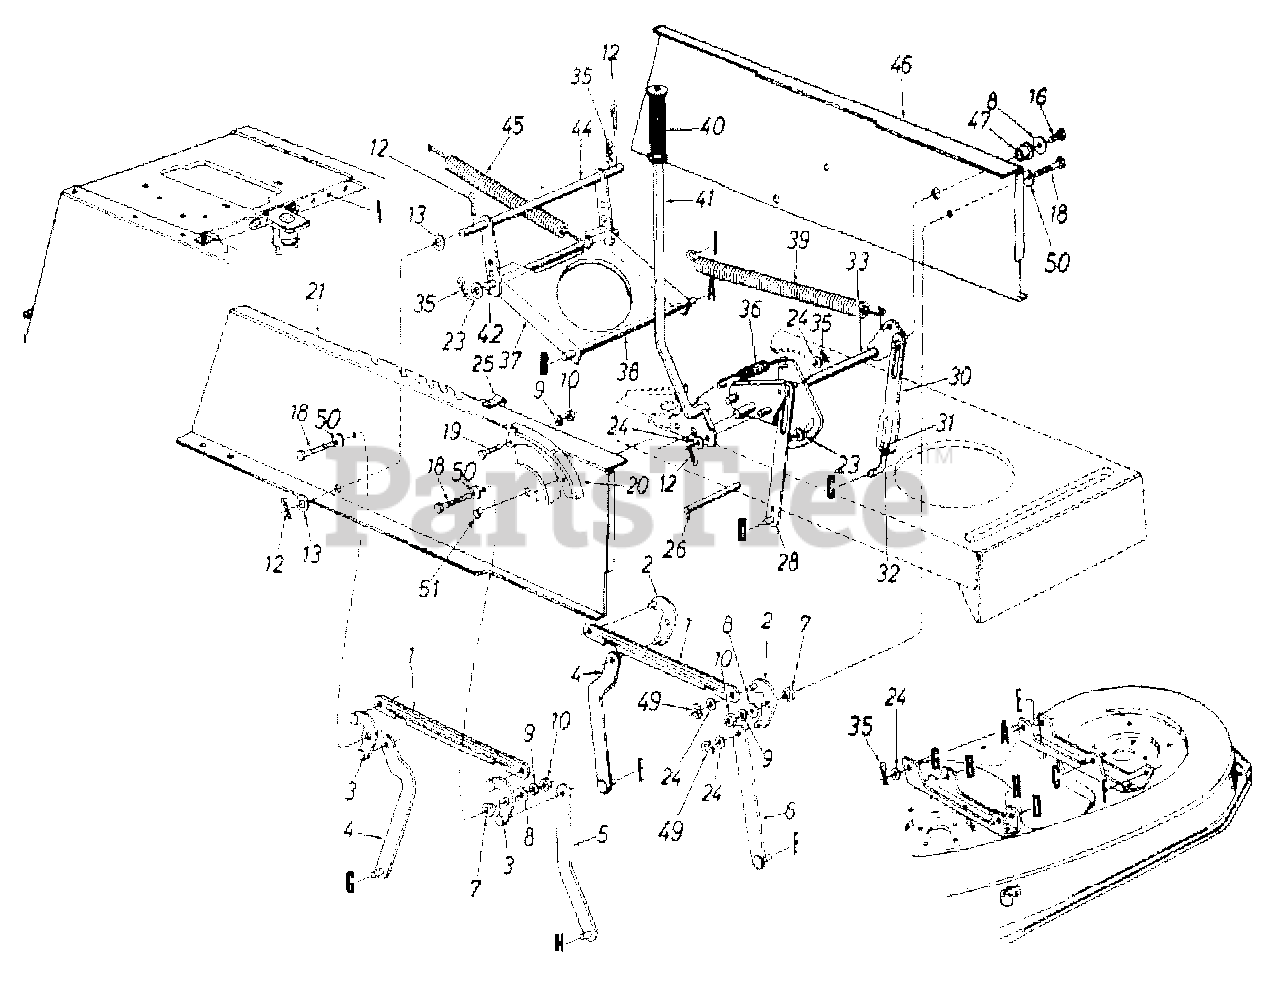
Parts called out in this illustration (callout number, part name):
3	Pivot Link Ass'y.-R.H.
7	Shld. Spacer .318" I.D.
8	Fl-Wash. .344" I.D. x .62" O.D.
9	L-Wash. 5/16" I.D.
10	Hex Nut 5/16-18 Thd.
12	Cotter Pin 1/8" Dia.
13	Fl-Wash. .635" I.D. x 1.0" O.D.
16	Hex Wash. TT-Tap Scr. 5/16-18 x .75" Lg.
18	Hex Wash. Hd. Scr. 5/16-18 x .875" Lg.
19	Hex Bolt 5/16-18 x .75" Lg.
24	Fl-Wash. .531" I.D. x .93" O.D.
26	Running Board Rod
31	Hex Nut 1/2-20 Thd. (Gr. 5)
32	Lift Link Adjuster
33	Lift Shaft Ass'y.
35	Inter. Cotter Pin 3/8" Dia.
36	Extension Spring
39	Extension Spring
40	Grip (Lift Handle)
41	Deck Lift Handle Ass'y.
42	Shaft 3/8" Dia. x 9.34" Lg.
44	Stabilizer Shaft Ass'y.
45	Extension Spring 7.58" Lg.
49	"E"-Ring
50	Bell-Wash. .325" I.D.
51	Flange Bearing .631 ID x .62 Lg.
